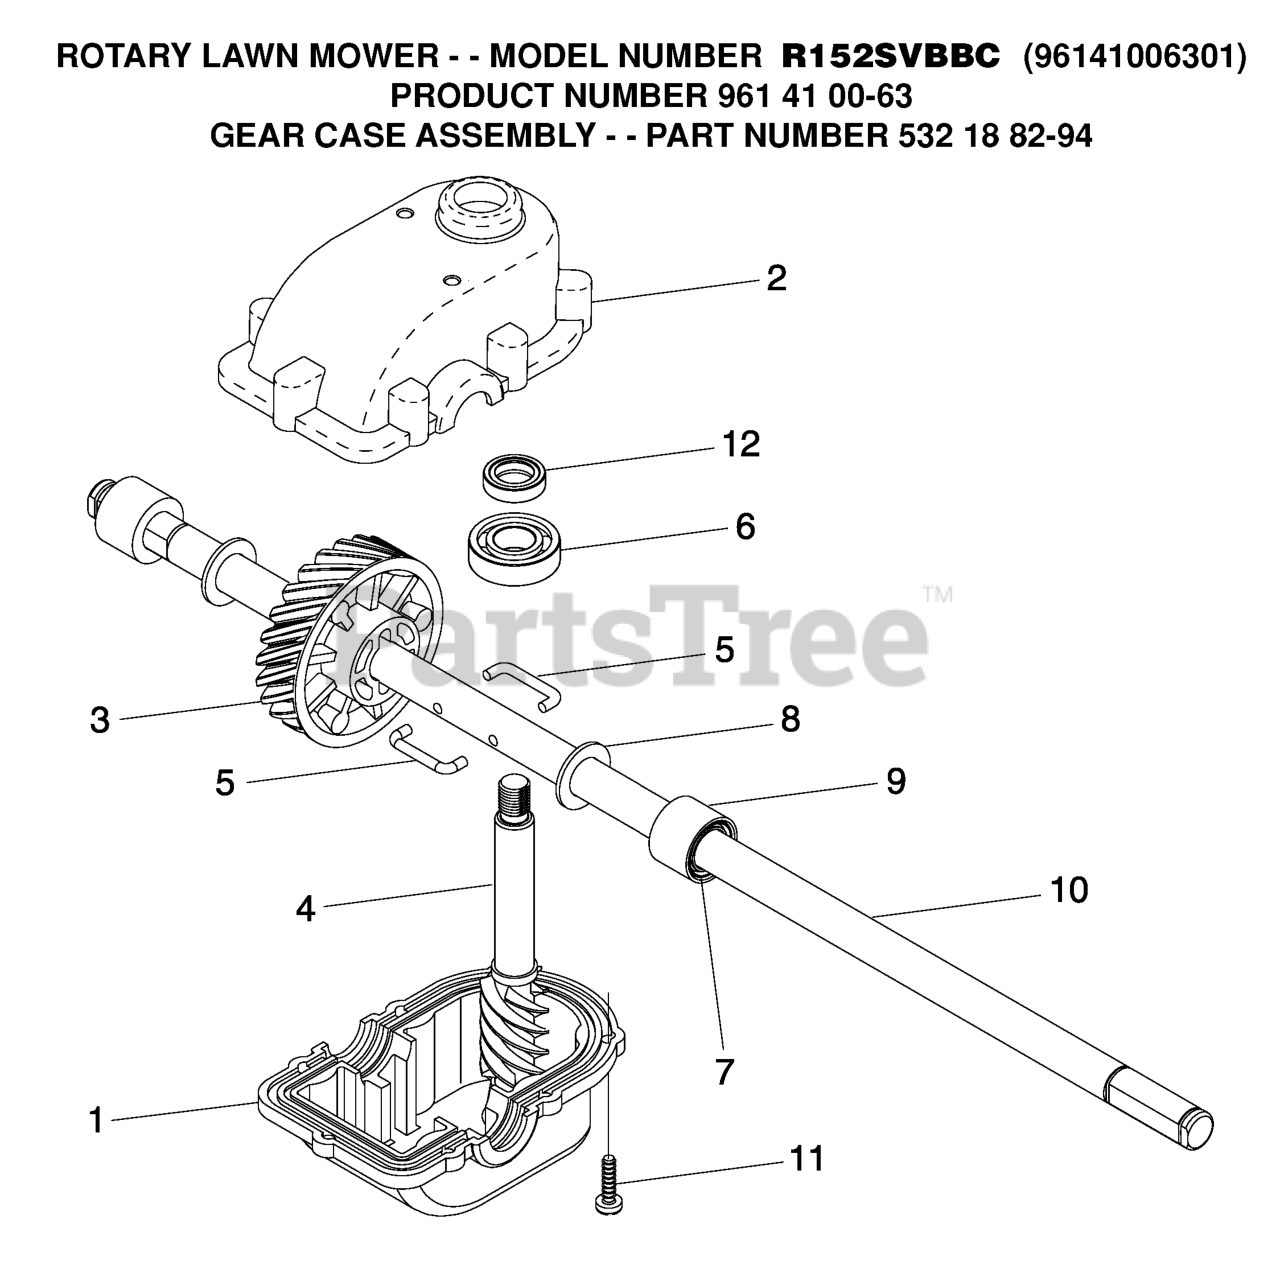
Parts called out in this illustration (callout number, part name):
1	CASE, LOWER
2	GEARCASE.HOUSING
3	GEAR.24.TOOTH.WALK.MOWER
5	WIRE, FORMED (15966)
7	SEAL.OUTPUT.SHAFT
10	SHAFT OUTPUT
12	SEAL INPUT SHAFT
